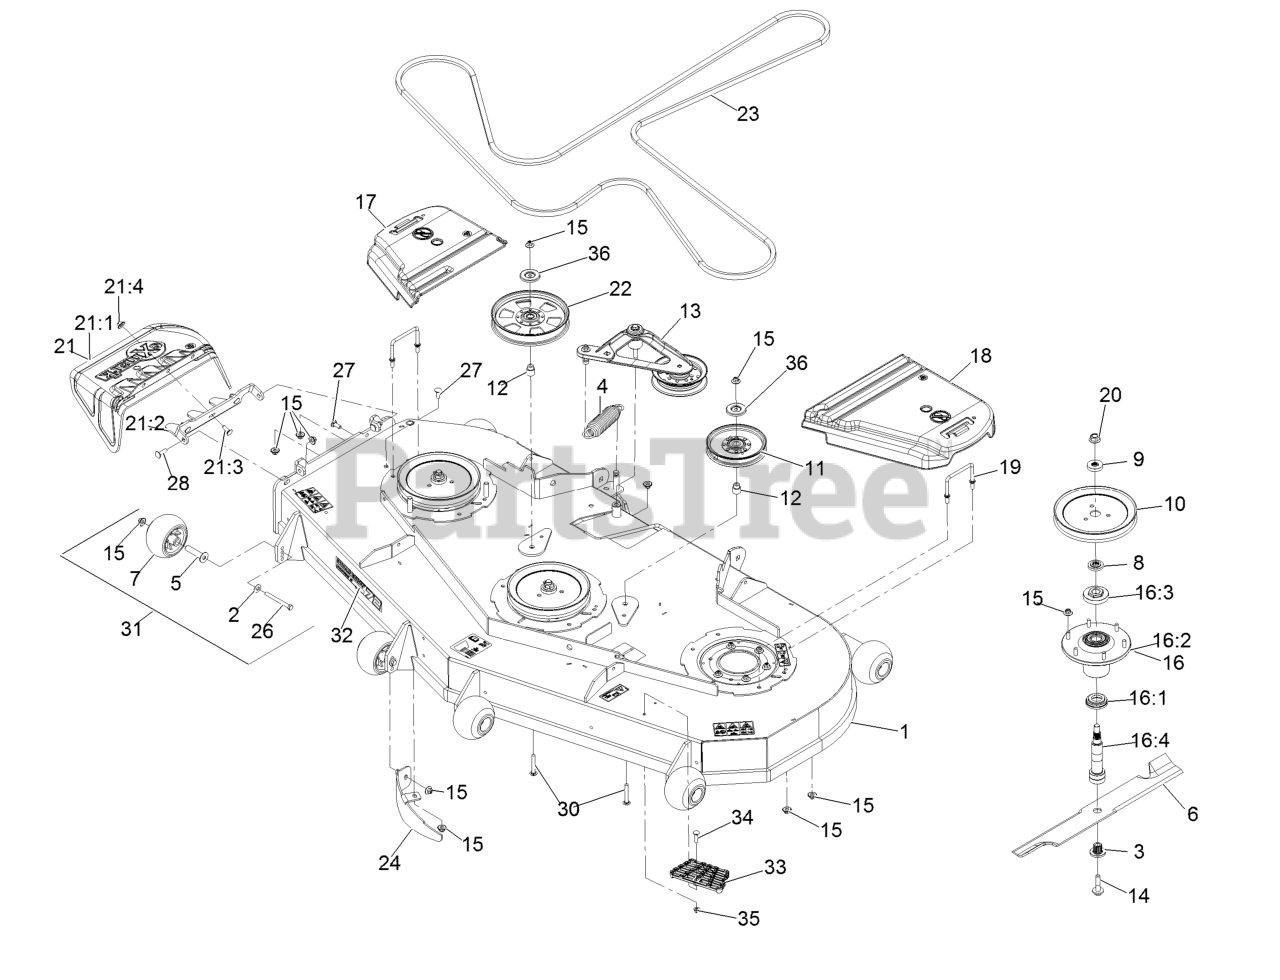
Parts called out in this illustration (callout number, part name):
1	ASM,Deck W/Decals 724
2	Washer-Belleville
3	Bushing, Splined
4	Spring-Extension
5	Axle, Roller
6	Blade, Solid (72")
6	Blade, Low Lift (72")
6	Blade, Mulching
6	Blade, Notched (72")
6	Blade-Extreme 2, 24.50"
7	Roller-Anti-Scalp
8	Spacer, Splined Stepped
9	Spacer, Splined
10	Sheave,Blade Drive 9.00
11	Idler-Pulley
12	Bushing, Idler
13	Deck Idler ASM
14	Screw-Sems 1/2-20 X 2.19
15	Nut-Nyloc 3/8-16 Flg
16	ASM,Spindle Housing
16:1	Guard, Bottom
16:2	Asm, Cutter Housing
16:3	Nut, Spindle 7/8-14
16:4	Spindle,Double Spline
17	Cover-Belt, RH
18	Cover-Belt, LH
19	Wireform-Cover
20	Nut-Flange 5/8-18 Centerlock
21	ASM,Discharge Chute
21:1	Chute, Discharge
21:2	Bracket,Discharge Chute
21:3	Bolt-Carriage 3/8-16 X 1
21:4	Nut-Nyloc 3/8-16 Flg
22	Pulley-Idler, Flat
23	Belt-V
24	Baffle-Dogleg, Lz72
26	Screw-HH
27	Bolt-Carriage 3/8-16 X 1
28	Bolt-Carriage 3/8-16 X 1 1/4
30	Screw-CARR
31	Kit, Anti-Scalp Roller
32	Decal, 726
33	Step-Deck
34	Bolt-Carriage 5/16-18 X 1 1/4
35	Nut-Nyloc 5/16-18 Flg
36	Shield-Dust
